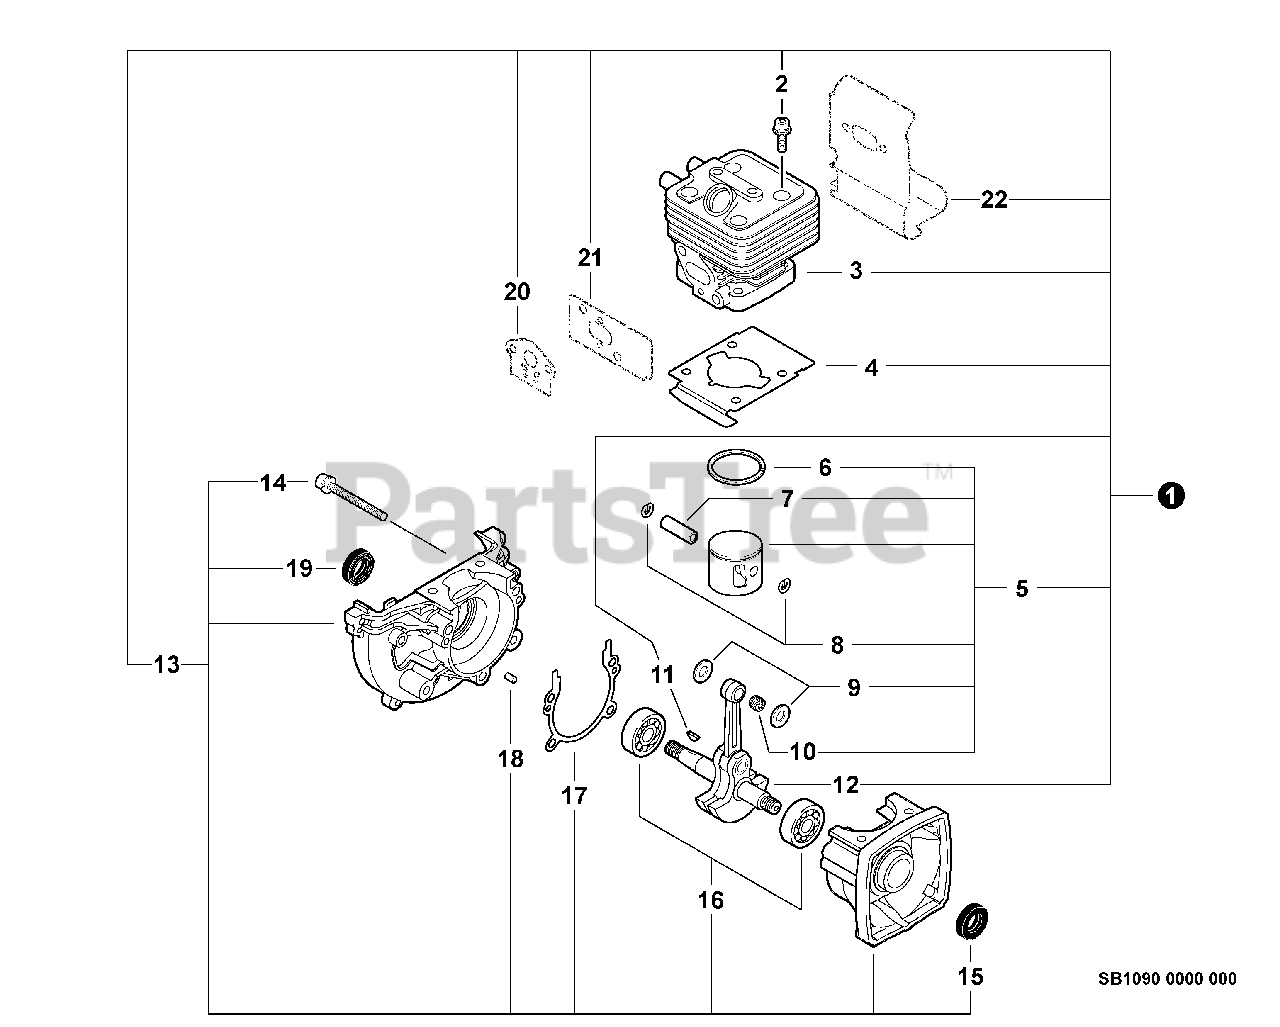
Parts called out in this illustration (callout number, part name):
1	SHORT BLOCK -- SB1090
2	SCREW - 5X25
3	CYLINDER
4	GASKET, CYLINDER
5	PISTON KIT
6	RING, PISTON
7	PIN, PISTON
8	RING, RETAINING
9	SPACER, PISTON
10	BEARING, NEEDLE
12	CRANKSHAFT ASSY
13	CRANKCASE KIT
14	SCREW - 5X28
15	SEAL, OIL
16	BEARING, BALL - 6201
17	GASKET, CRANKCASE
18	PIN - LOCATING
19	SEAL, OIL
20	GASKET, INTAKE
21	GASKET, INTAKE
22	SHIELD, EXHAUST
